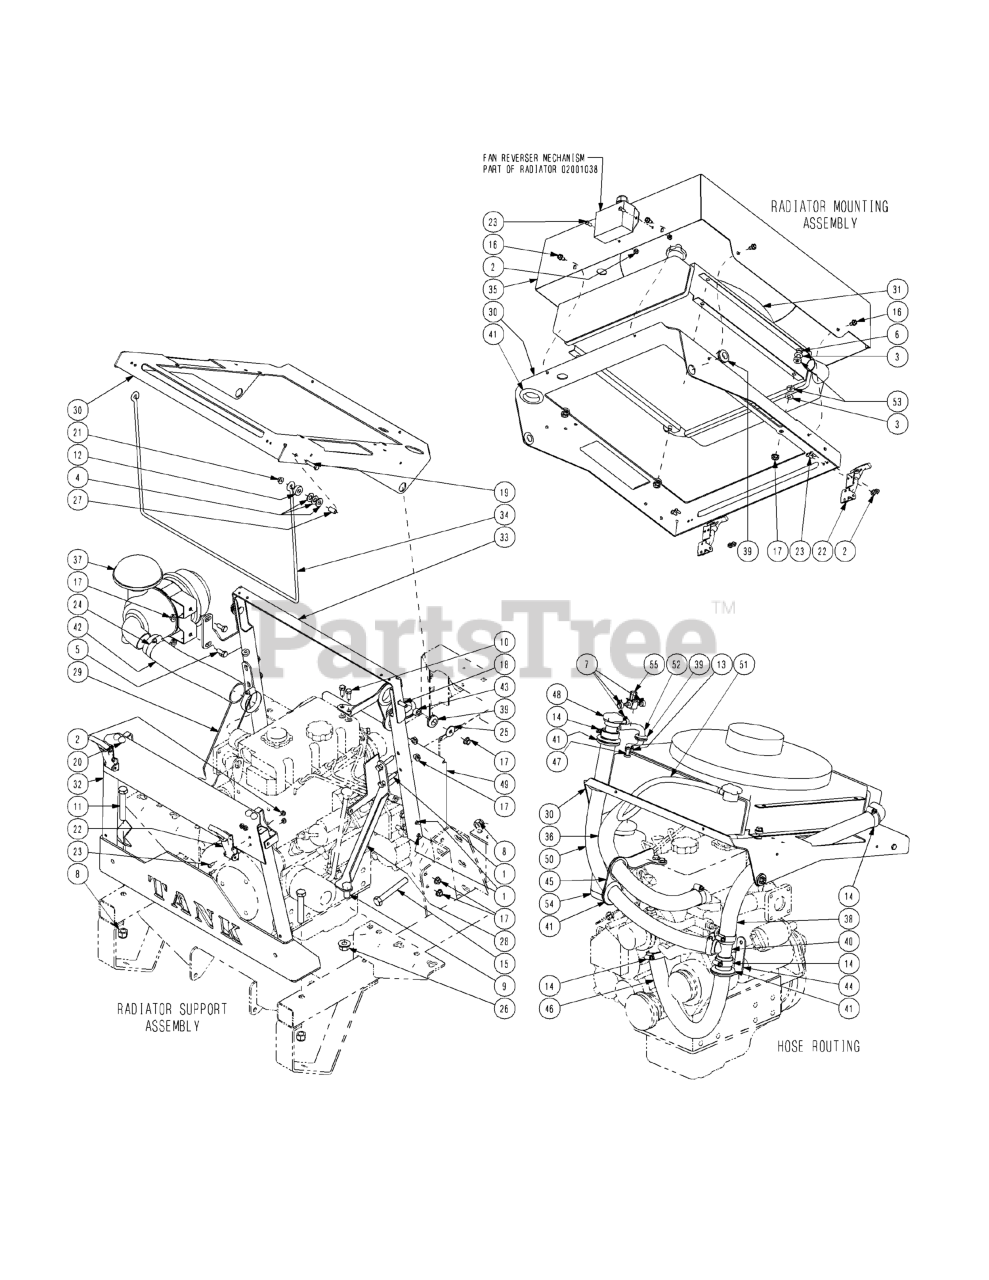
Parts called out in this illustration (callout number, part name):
1	Hex Cap Screw, 5/16-18 x 1.75
2	Nut, 10-24, Nylon Insert
3	Flat Washer, 5/16
4	Flat Washer, 3/8
5	SCREW 5/16-18 x .750 GR8
6	Hex Head Cap Screw, 5/16-18 x 1.00
7	Hose Clamp
8	Nut, 1/2-13, Nylon Insert
9	Hex Cap Screw, 1/2-13 x 1.00
10	Hex Cap Screw, M8-1.25 x 18mm
11	Hex Head Cap Screw, 1/2-13 x 3.00
12	Spacer, Control Rod
13	Hose Clamp, 1/4-5/8
14	Hose Clamp,, 7/8:1-1/4
15	Hex Cap Screw, 1/2-13 x 3.50
16	Screw, TT, 1/4-20, 0.5, Hex Index Washer
17	HEX FLANGE NUT
18	Carriage Bolt, 5/16-18 x 1.00
19	Hex Cap Screw, 1/4-20 x 1.25
20	Rubber Bumper, .62 OD x .22 Thick
21	Lock Nut, 1/4-20
22	T-Handle Latch Draw
23	Hex Cap Screw, 10-24 x 1/2
24	Hose Clamp
25	Washer, 5/16 x 1.06
26	Nut, 1/2-13, FlangeLock
27	Spacer, .259 x .375 x .707
28	Radiator Support Gusset, RH
29	Radiator Support Gusset, LH
30	Radiator Mounting Bracket
31	Radiator includes:
32	Radiator Mounting Assembly
33	Radiator Mounting Assembly
34	Radiator Stand
35	Radiator Shroud Assembly
36	Radiator Hose, 1.12 ID x 36" Long
37	Air Filter Assy includes:
38	Radiator Hose 1.12 x 22.5" Long
39	Gromment, .62 ID x 1.13 OD
40	Tee Adaptor
41	Gromment, 1.5 ID x 2.13 OD
42	Air Hose, 1.75 ID
43	Spacer, .625 OD x .407 ID x .375
44	Radiator Hose Bracket
45	Radiator Hose Bracket
46	Radiator Hose, 1.12 ID x 18" Long
47	Elbow Adaptor, 1/8 NPT x 1/4
48	Neck Filler Adaptor
49	Belt Shield
50	Radiator Hose, 1" ID x 28.5" Long
51	Radiator Hose, 1/4" x 27"
52	Radiator Hose, 1/4" x 9"
53	Flat Rubber Washer, 1/4
54	Over Flow Coolant Container
